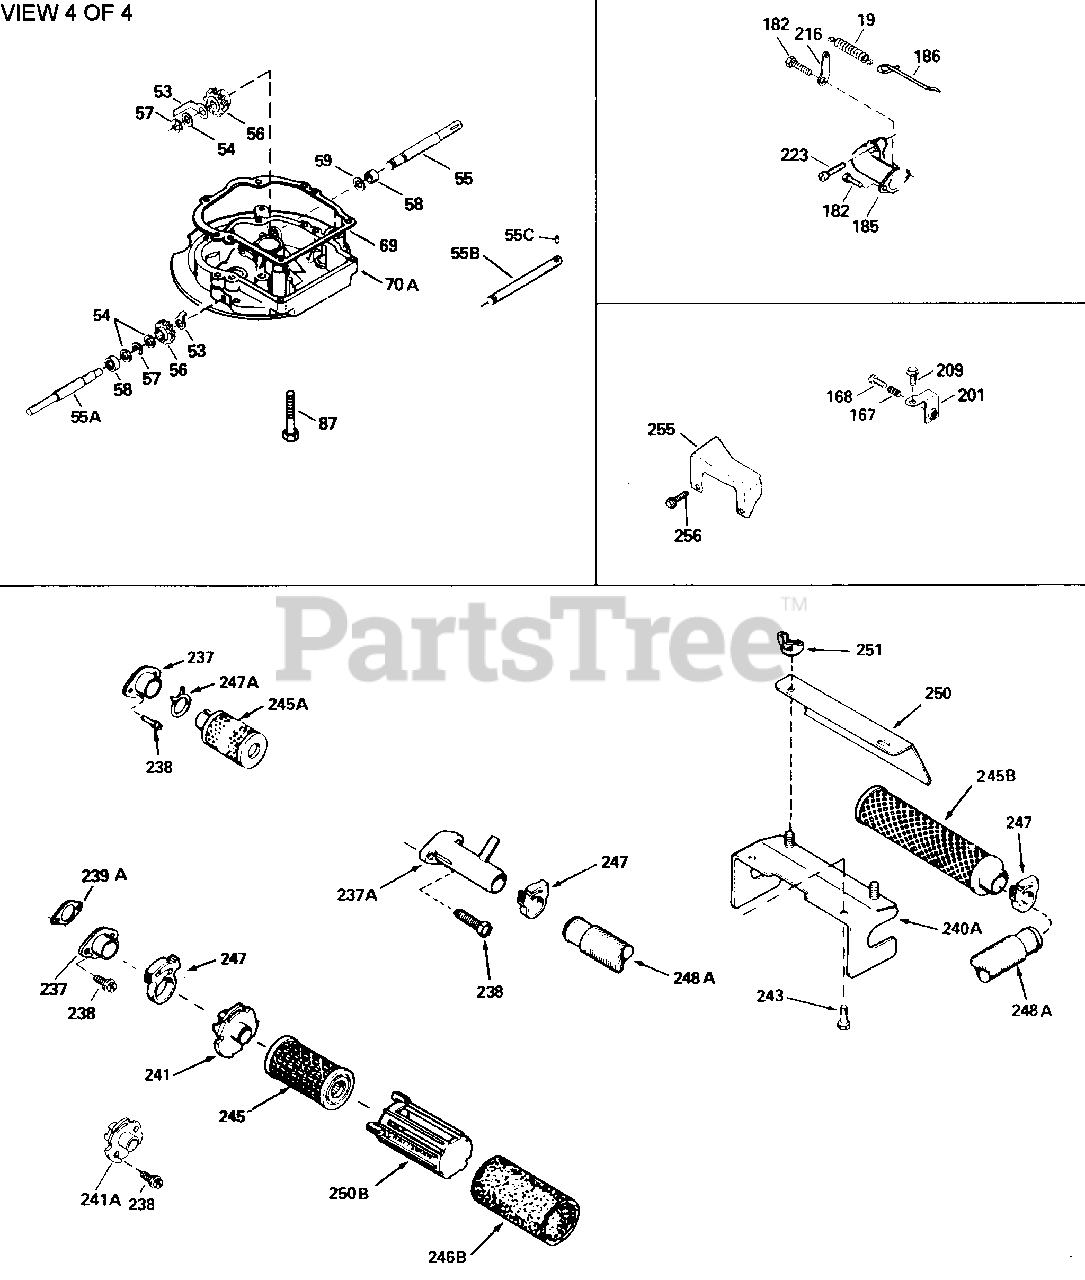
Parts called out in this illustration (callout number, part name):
19	Spring, Extension
69	* Gasket, Mounting flange
182	Screw, 1/4-28 x 7/8"
185	Pipe, Intake (Incl. 224)
186	Link, Governor spring
209	Screw, 10-24 x 9/16"
223	Screw, 1/4-20 x 1"
241	Collar, Air cleaner (Black)
245	Air Filter (Paper) (also available in Packaged Part #740095 (Qty.2))
246B	Filter, Pre-Air (Use as required)
247A	Clamp, Air cleaner
250B	Air Filter Cover (Craftsman)
255	Cover, Speed control
999	Summer Maintenance Kit (incl. Oil, Sp ark Plug, Air Cleaners (2), & Ultra-F resh)
